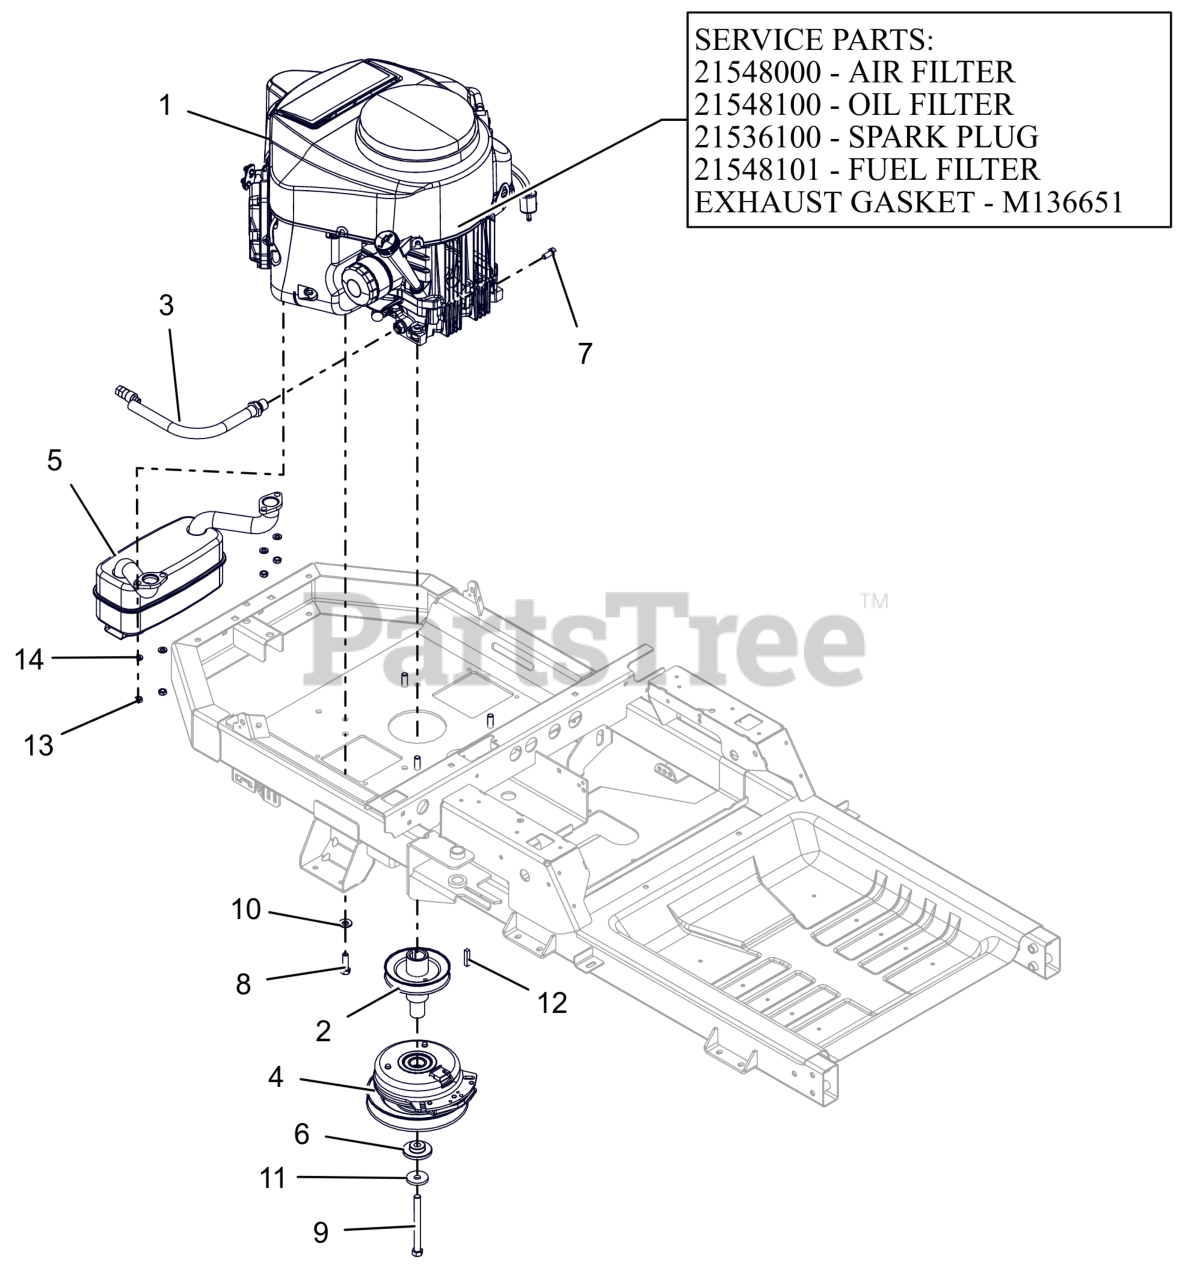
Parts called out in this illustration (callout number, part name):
1	ENGINE, KAWASAKI FR691 23HP
1	AIR FILTER, KAWASAKI FR
1	OIL FILTER, KAWASAKI FR
1	PLUG, SPARK
1	FUEL FILTER-KAWASAKI FR
1	GASKET, MUFFLER #
2	WLDMT, DRIVE SHEAVE-X
3	HOSE, OIL DRAIN
4	CLUTCH,105FTLB MONOPOLE 6.83"
5	MUFFLER - KAWASAKI
6	BSHG-FLG .469X1.06X.574X2.0
7	BLT, HEX M8-1.25X20 G8.8 ZCC
8	BLT, HEX .38-16X1.25 G5 ZCC NT
9	BLT, HEX .44-20X4.50 G8 ZCC NT
10	WASHER, 3/8" SPRING DISC
11	WASHER, 7/16" SPRING DISK
12	KEY-SQ .25 X 1.25 X .25 SAE
13	NUT, LK-CTR-JAM M8-1.25 GR8.8 ZC120
14	WSHR,LK-REG .312X.078 ZCC
